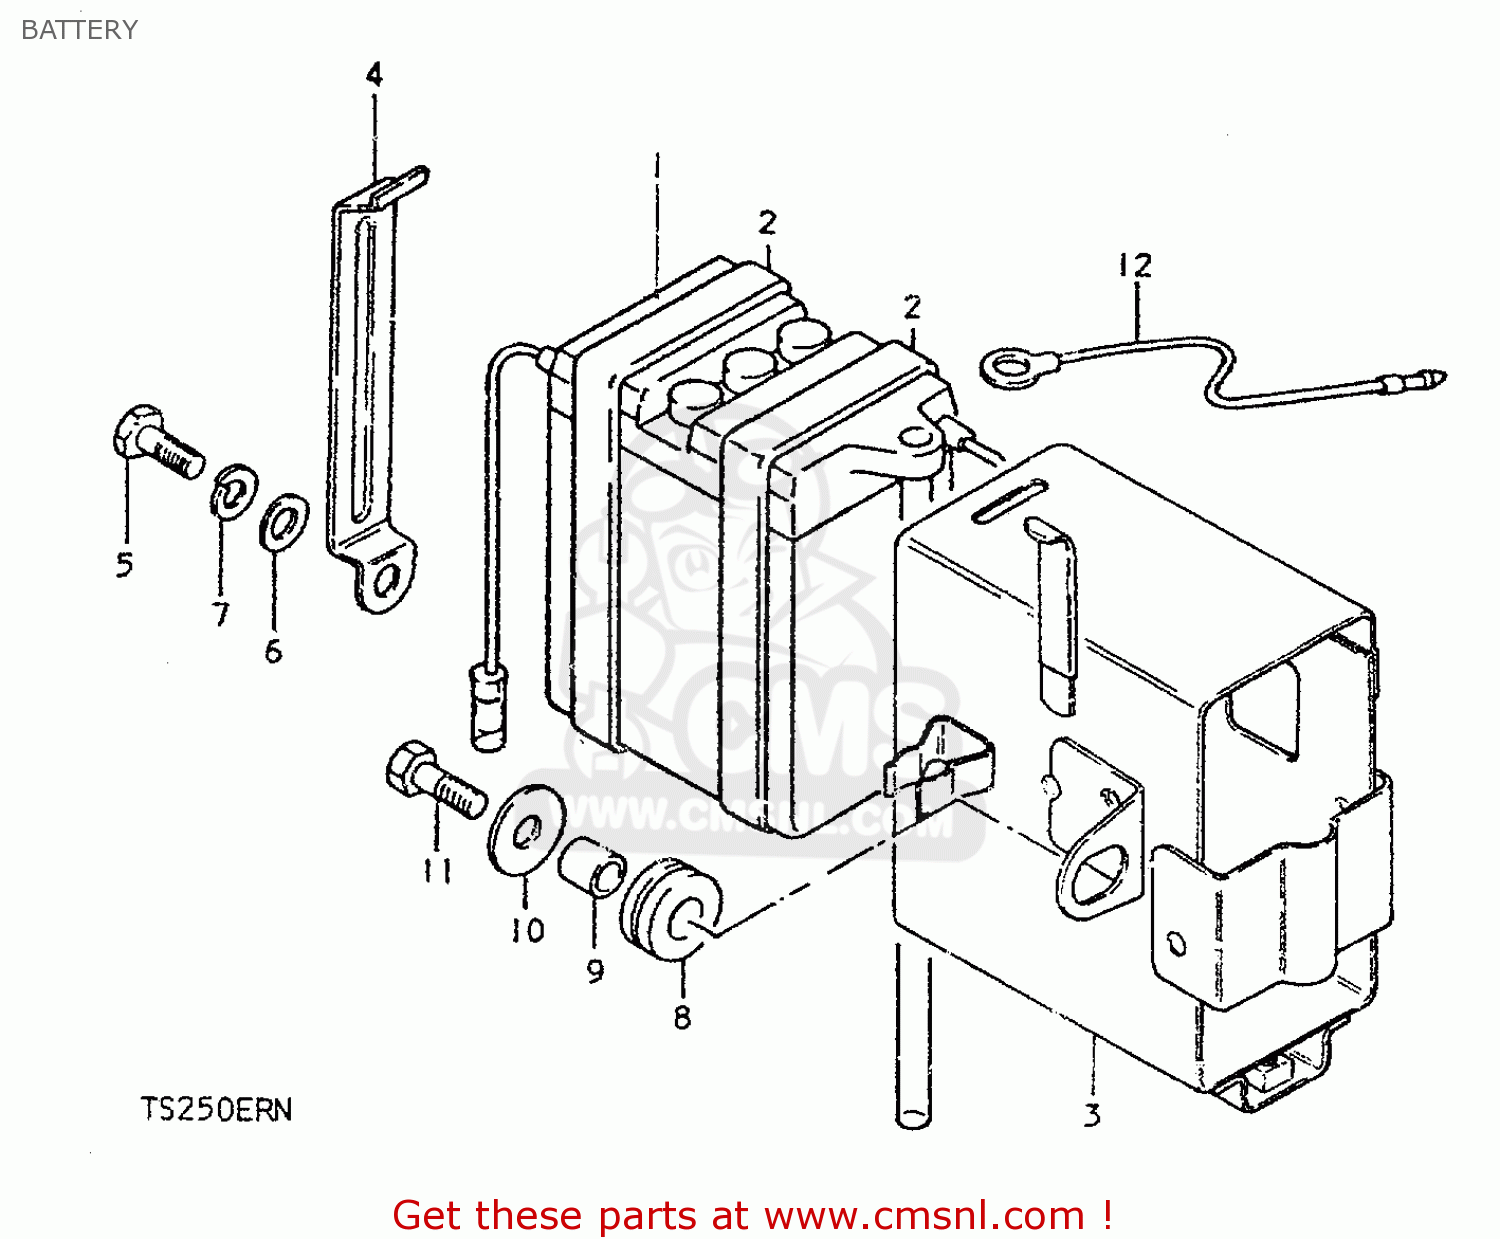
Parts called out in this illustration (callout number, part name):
1	BATTERY(6N4B-2A,6V4.2AH)
2	PROTECTOR,BATTERY
3	HOLDER,BATTERY
4	PLATE, HOLDER
5	SCREW(6X10)
6	WASHER
7	LOCK WASHER
8	CUSHION
9	SPACER (7X9X7)
10	WASHER (6.5X20X1.2)
11	SCREW
12	LEAD WIRE
